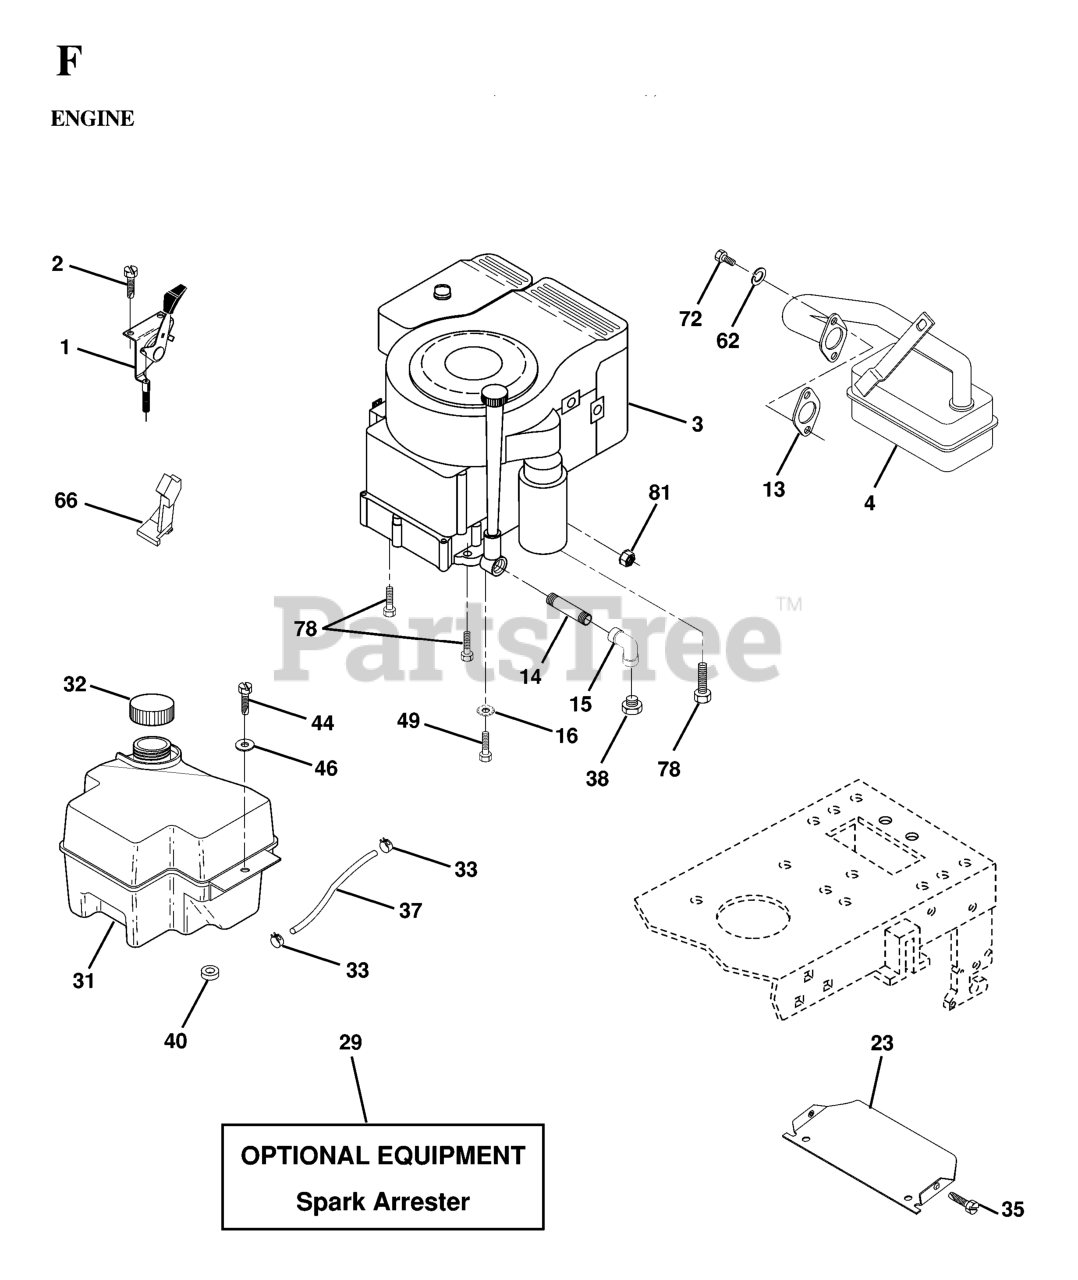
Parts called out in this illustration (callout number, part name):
1	CONTROL
2	SCREW LT
4	MUFFLER.LT.BRIGGS.14HP.IC/OHV
13	GASKET.ENG.1.313 ID.TIN PLATED
14	Nipple Pipe 3/8 Npt X 3-1/2
15	ELBOW
16	LOCKWASHER
23	SHIELD HEAT
29	KIT.SPARK ARRESTOR 794945 B&S
31	FUEL TANK
32	FUEL CAP
33	HOSE CLAMP
35	SCREW.THDROL.5/16-18X3/4.TTY
37	LINE.FUEL.20
40	BUSHING.SNAP.NYL.BLK.
44	SCREW HEX CRT
49	SCREW GTV
62	WASHER.LOCK.HVY.HLCL.SPR.5/16
66	STOP THROTTLE
72	SCREW
78	SCREW
81	NUT FLANGE 1/4-20 STARTER NUT
